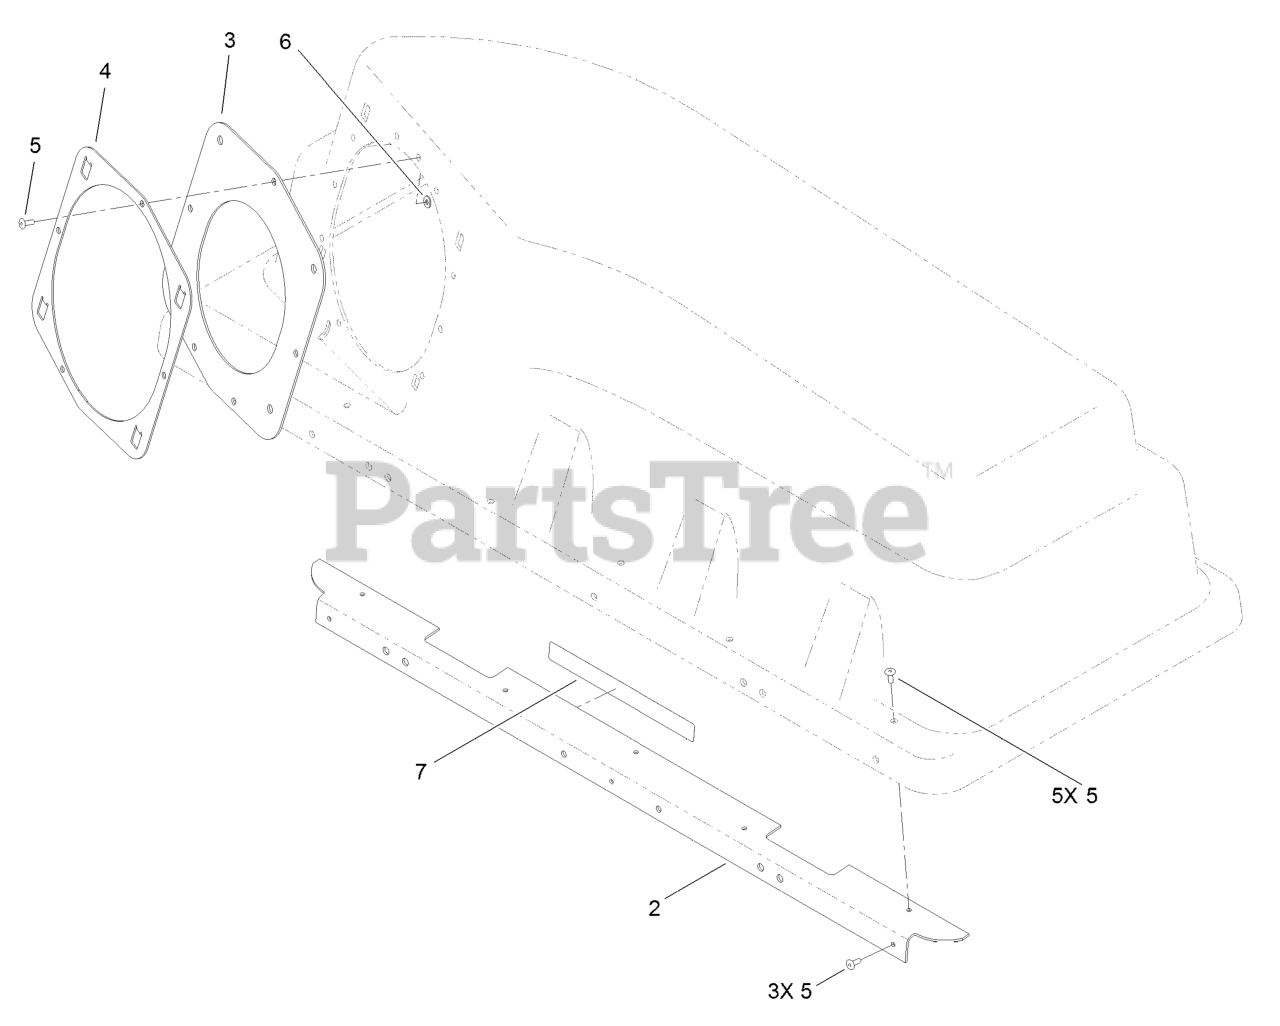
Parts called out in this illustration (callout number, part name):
2	STIFFENER-BAGGER TOP
4	RING-RETAINER
5	RIVET-BLIND
6	WASHER-FLAT
7	DECAL-CAUTION, BAGGER
